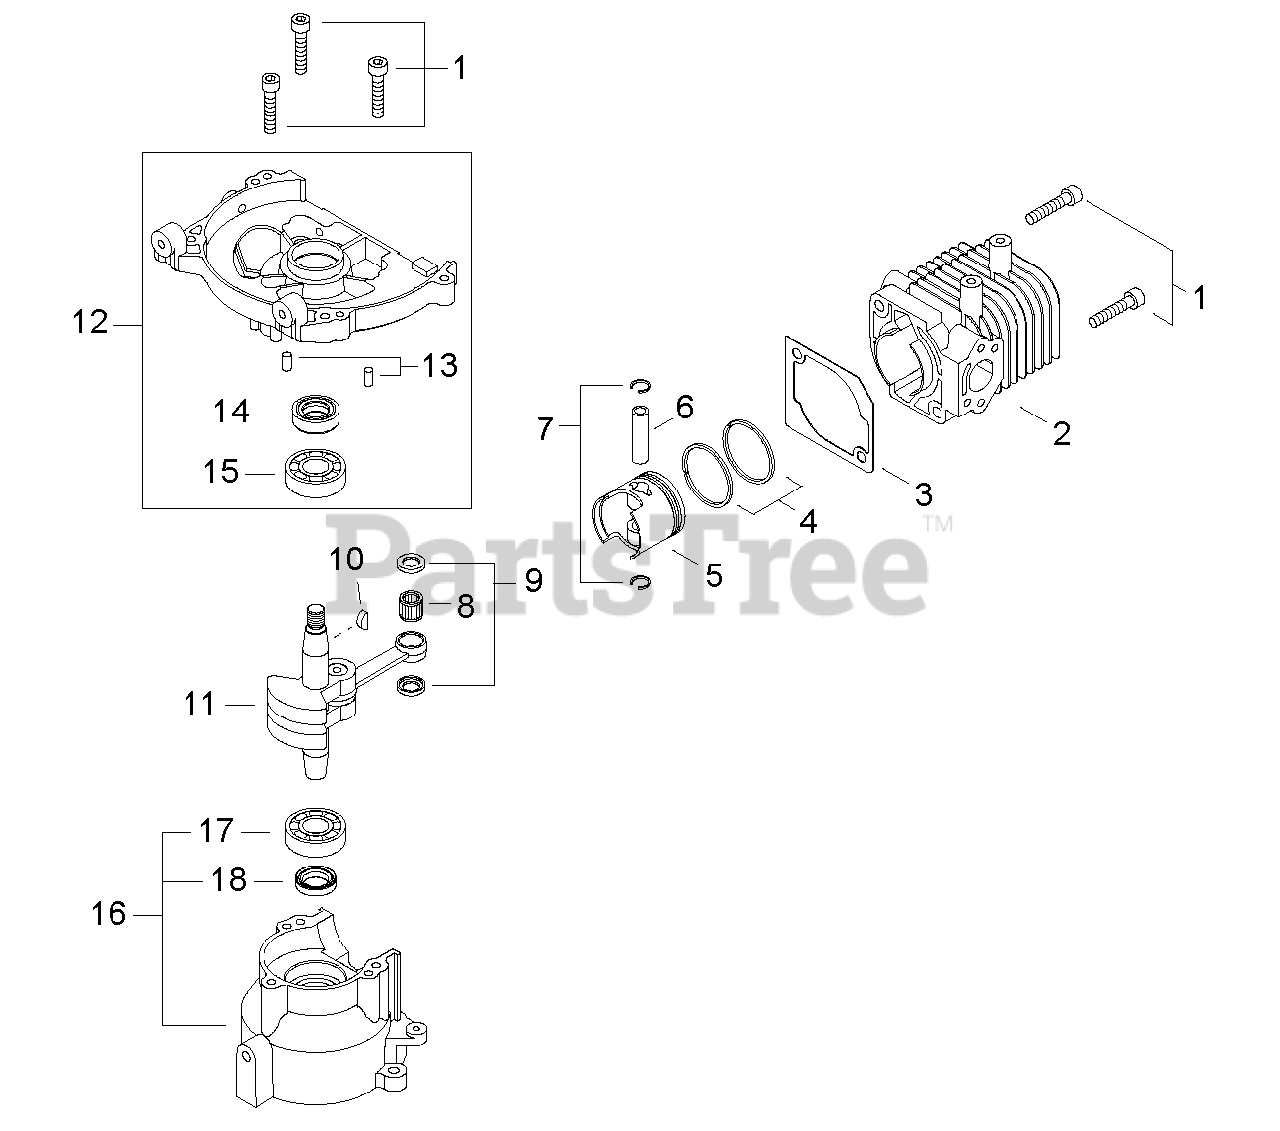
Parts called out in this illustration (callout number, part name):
1	BOLT 5×25
2	CYLINDER
3	GASKET, CYLINDER
4	RING, PISTON
6	PIN, PISTON 8
7	RING, SNAP
8	BEARING, NEEDLE 8
9	WASHER, THRUST 8
10	KEY, WOODRUFF 3×10
11	CRANKSHAFT ASSY
12	CRANKCASE ASSY, M
13	PIN, LOCATING Ø4×8
14	SEAL, OIL 12
15	BEARING, BALL 6001 C3
16	CRANKCASE ASSY, PTO
17	BEARING, BALL 6001 C3
18	SEAL, OIL 12
